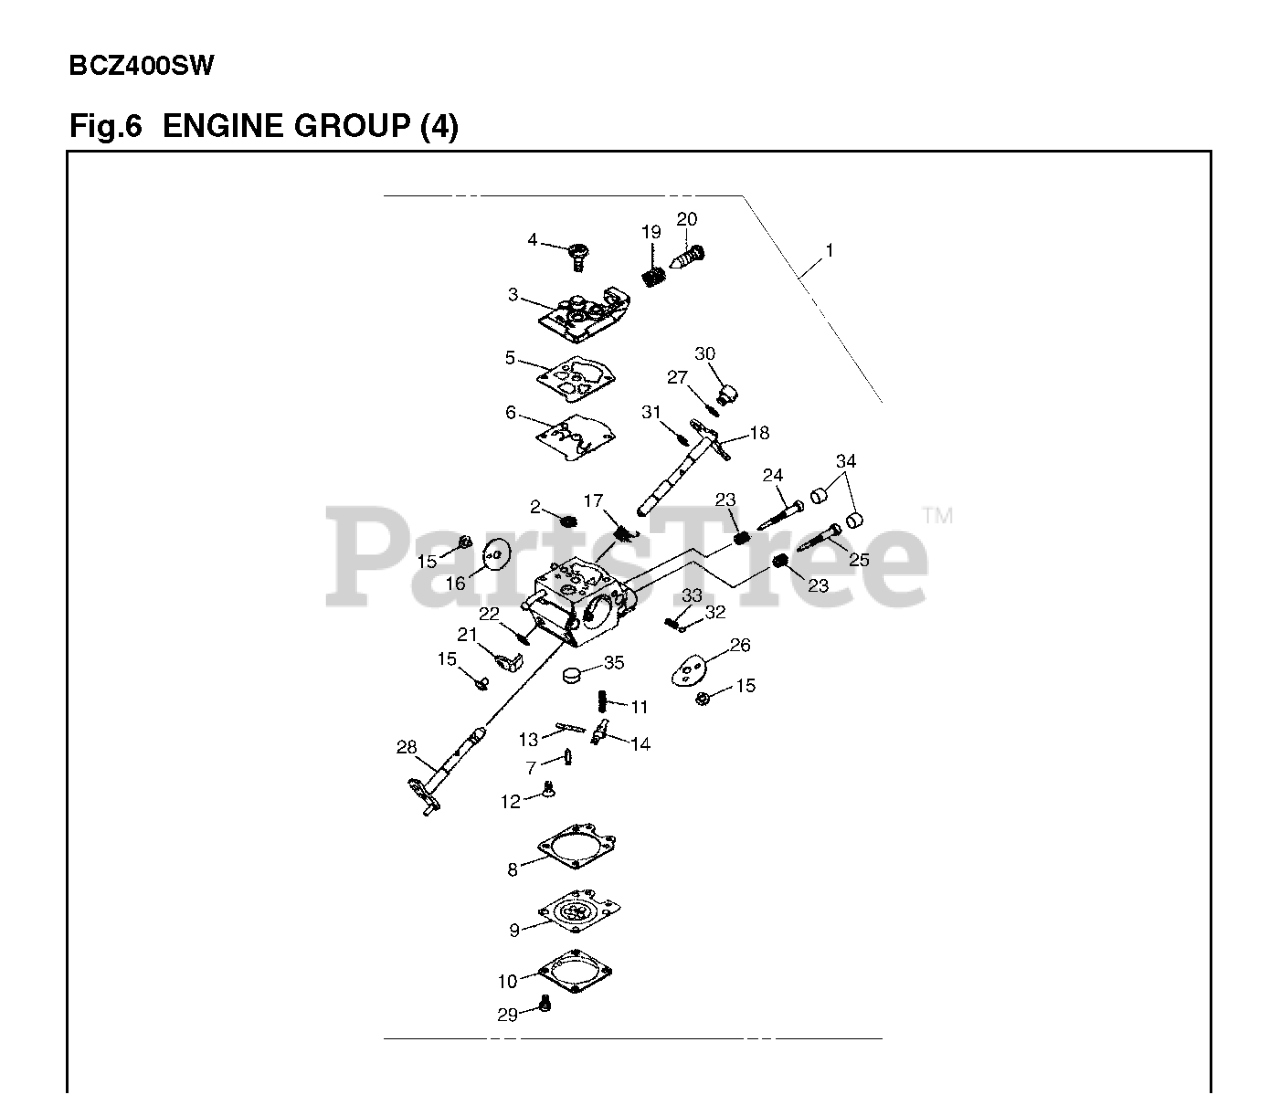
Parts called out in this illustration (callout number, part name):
1	CARBURETOR ASSY WTEA-4A
2	SCREEN
5	GASKET
6	DIAPHRAGM
7	VALVE INLET
8	GASKET
9	DIAPHRAGM
15	SCREW
16	VALVE, THROTTLE
18	SHAFT ASSY THROTTLE
20	SCREW, IDLE
21	LEVER THROTTLE
24	NEEDLE L
25	NEEDLE H
26	VALVE CHOKE
28	SHAFT ASSY CHOKE
29	SCREW ASSY
31	RING
33	CHOKE SPRING
34	CAP LIMITER
